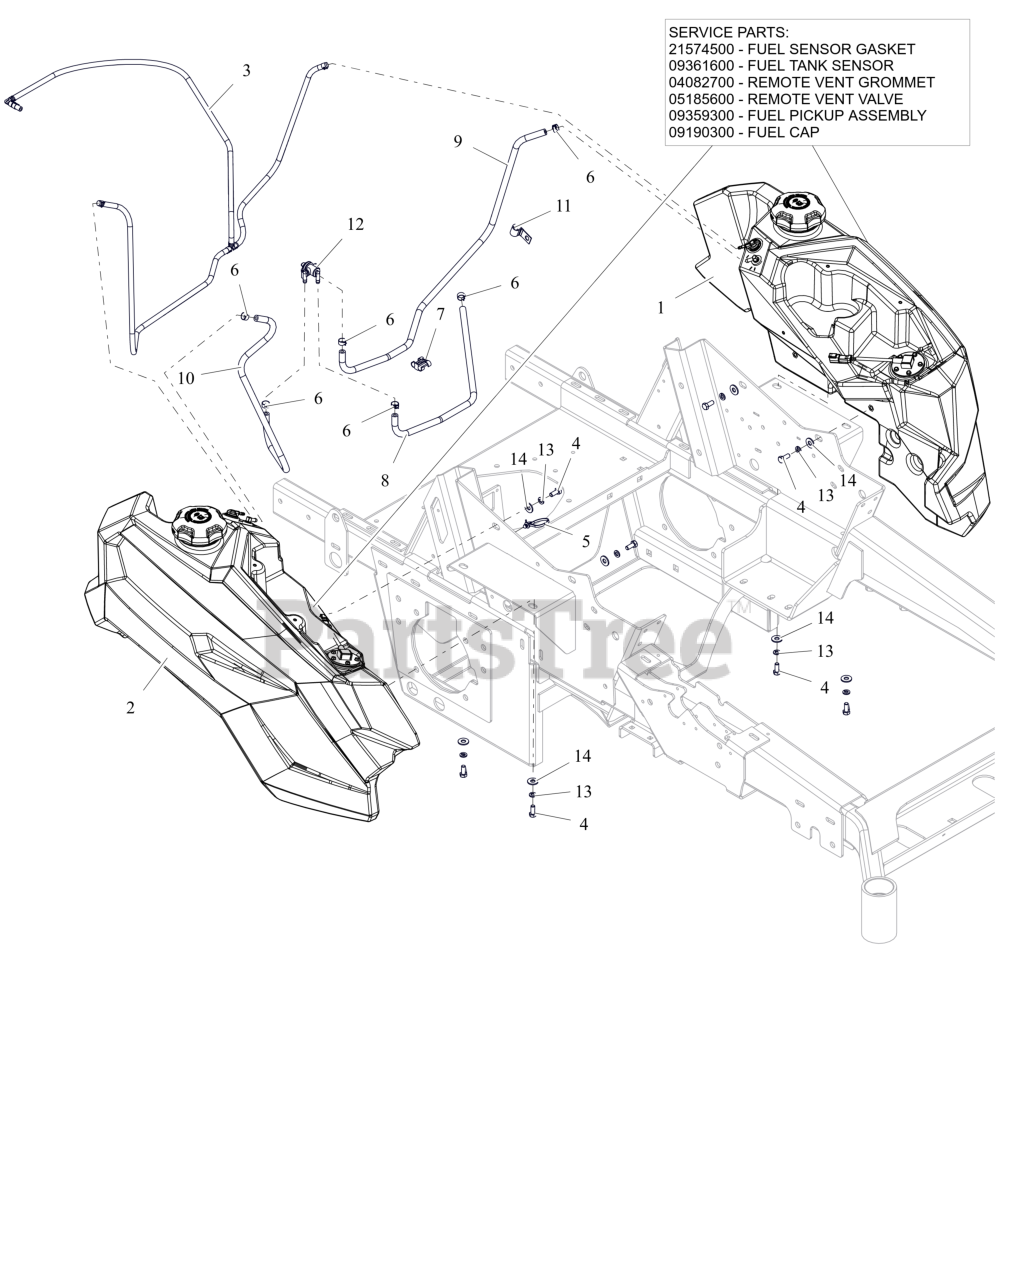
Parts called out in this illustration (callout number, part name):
1	ASM, LH FUEL TANK
1	FUEL TANK SENSOR GASKET
1	FUEL TANK SENSOR
1	GROMMET, REMOTE VENT NITRILE
1	VALVE, COMBINATION VENT 3/16
1	FUEL PICKUP ASSEMBLY
1	CAP, FUEL - 3.50 RATCHET INLET VENT
2	ASM, RH 421 FUEL TANK
3	ASM, KAWASAKI NON-EFI VAPOR LINE
4	BLT,HEX .31-18X.75 G5 ZCC
5	CABLE TIE W/ TREE (.25 HOLE)
6	CLAMP, FUEL LINE
7	CLIP, T, .38-.50
8	1 INCH OF HOSE, .25 LOW-PERM BULK GAS
9	1 INCH OF HOSE, .25 LOW-PERM BULK GAS
10	1 INCH OF HOSE, .25 LOW-PERM BULK GAS
12	VALVE, FUEL - WITH MAGNET
13	WSHR,LK-REG .312X.078 ZCC
14	WSHR,FLT .375X.875X.083 ZCC
